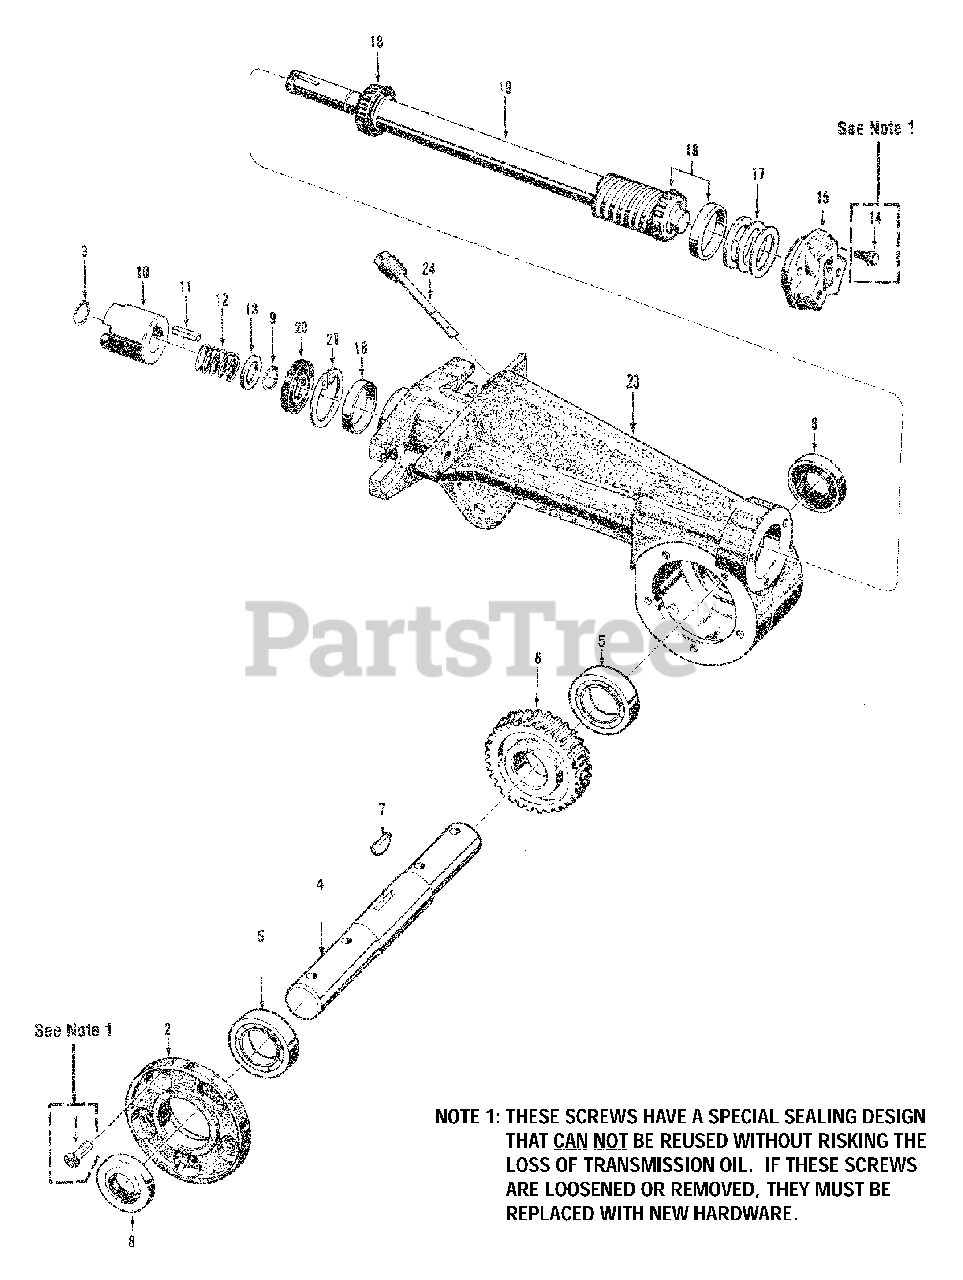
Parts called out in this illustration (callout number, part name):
1	Screw-self-sealing,1/4"-20 x 5/8"
2	Cover-tiller housing
4	Shaft-tiller tine
5	Ball Bearing
6	Worm Gear-bronze, tiller tine shaft
7	Key-tiller tine shaft, woodruff key.
8	Seal-oil, tiller tine shaft
9	Retaining Ring-external
10	Dog Clutch-tiller drive shaft
11	Key-3/16" x 1"
12	Spring-dog clutch
13	Shim-dog clutch, 1/16"(.62") thick
14	Screw-self-sealing,1/4"-20 x 7/8"
15	Cap-rear bearing
17	Shim-front bearing cap, .010" thick
17	Shim-same as above, .030" thick
17	Shim-same as above, .005" thick
17	Shim-same as above, .062" thick
18	Bearing & Race
19	Shaft-main tiller drive
20	Seal-oil, drive shaft, front
21	Retaining Ring-internal
23	Housing-tiller attachment
24	Dipstick-oil, tiller attachment
